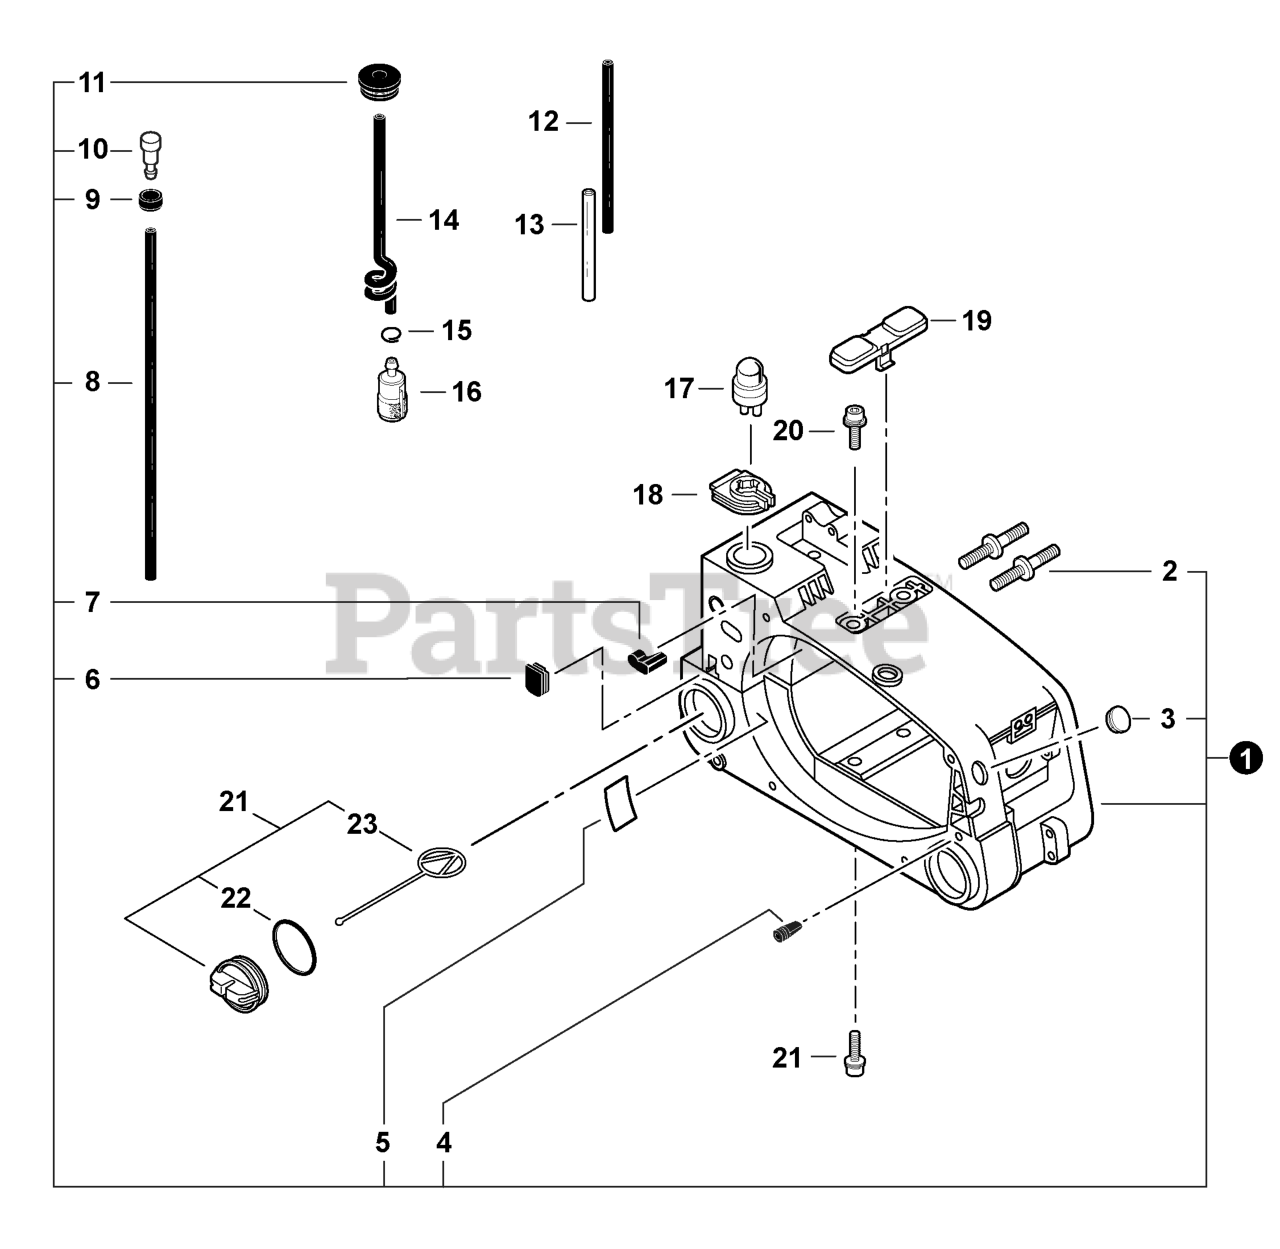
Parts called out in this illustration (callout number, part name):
1	COVER ASSY, ENGINE
2	BOLT, STUD 6
4	VENT ASSY
5	SHIELD, HEAT
8	PIPE, FUEL 3x5x150 BLACK
9	HOLDER, VENT
10	VENT ASSY
11	GROMMET, FUEL
12	PIPE, FUEL 3x5x70 BLACK
13	PIPE, FUEL 2x4x42 CLEAR
14	PIPE, FUEL 3x6x160
15	CLIP 6.5 MM
16	FILTER, FUEL
17	BULB, PURGE
18	BRACKET, BULB
19	COVER, TOP
20	BOLT 5x16
21	CAP ASSY, FUEL - ORANGE
22	O-RING 25
23	CONNECTOR, CAP L= 60 MM
